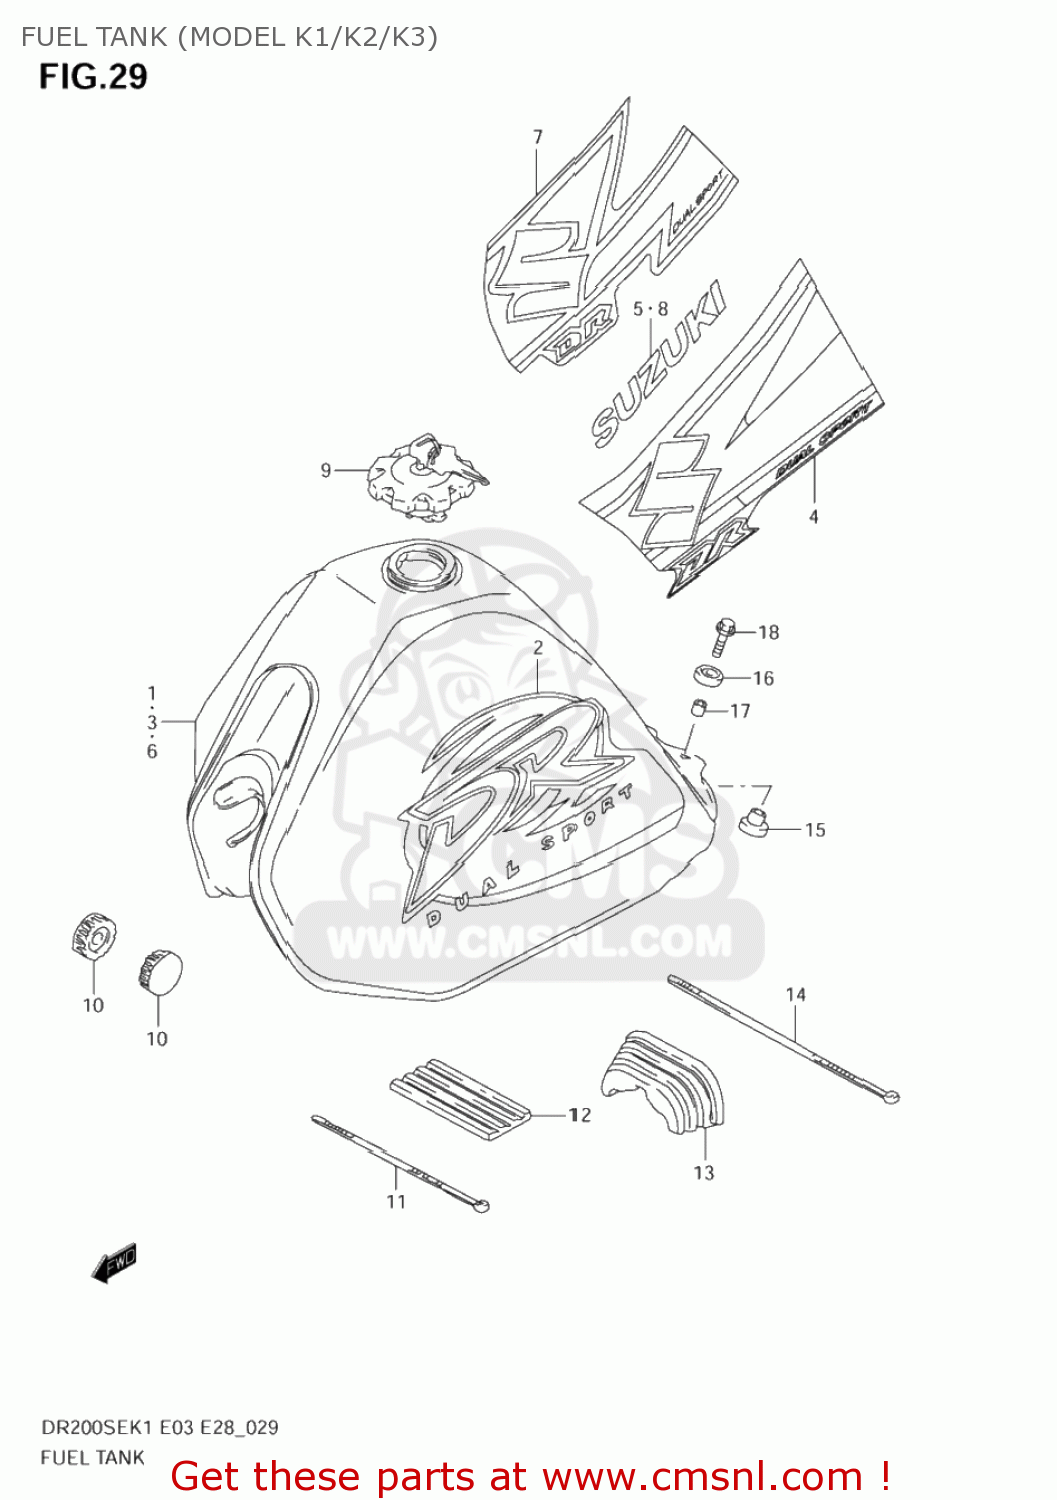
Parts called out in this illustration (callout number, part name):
1	TANK ASSY,FUEL(BLUE)
2	TAPE SET,FUEL TANK
3	TANK ASSY,FUEL(YELLOW)
4	TAPE SET,FUEL TANK
5	EMBLEM,FUEL TANK
6	TANK ASSY,FUEL(YELLOW)
7	TAPE SET,FUEL TANK
8	EMBLEM (WHITE)
9	CAP SET,FUEL TANK
10	CUSHION
11	CLAMP(L:250)
12	CUSHION,FUEL TANK UPR FR
13	CUSHION,FUEL TANK RR
14	CLAMP(L:300)
15	CUSHION
16	CUSHION
17	SPACER(6.5X9X18)
18	BOLT
